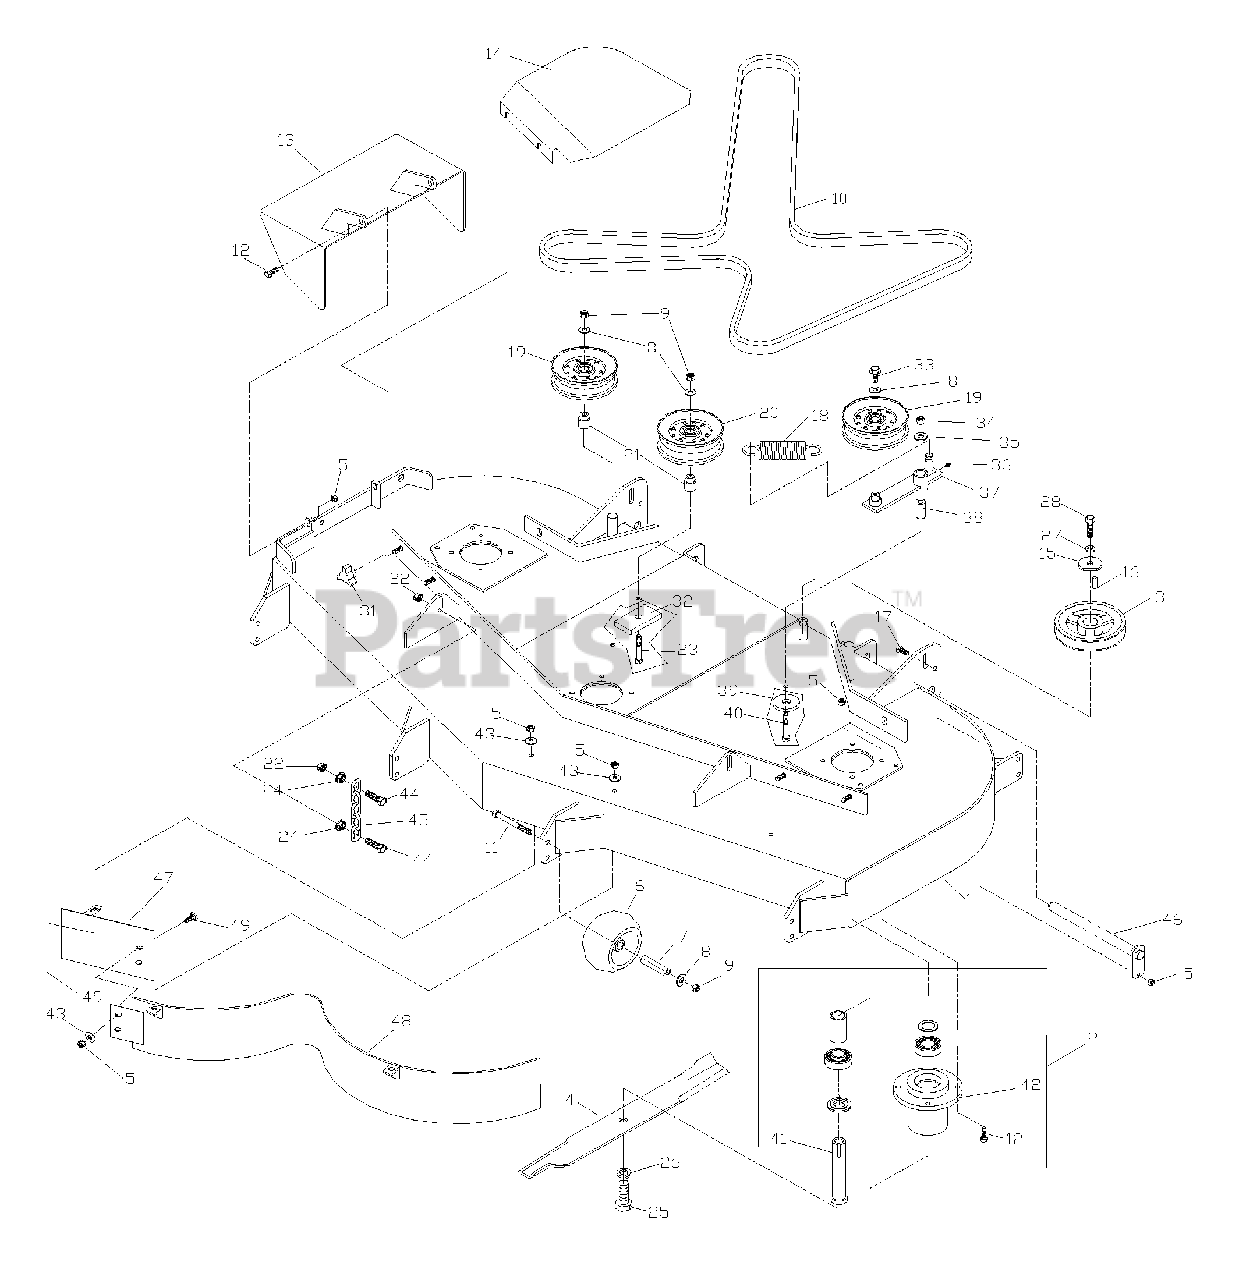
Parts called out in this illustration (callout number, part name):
1	DECK W/DECALS
2	CUTTER HOUSING ASM
2	BEARING KIT, CUTTER HOUSING
4	BLADE, 21"
5	NUT 5/16 LOCK
8	3/8 FLAT WASHER
9	NUT 3/8 LOCK
10	BELT
11	HCS 3/8 X 3.5
12	HCS 5/16 X 1.00
13	DISCHARGE CHUTE
14	BELT SHIELD RT
14	BELT SHIELD LT
16	KEY 1/4 SQ
17	HCS 5/16 X 750
19	PULLEY 1.31
20	PULLEY 1.62
21	IDLER BUSHING
22	NUT 7/16 LOCK
23	HCS 3/8 X 2.5
24	NUT 7/16 WHIZ
25	HCS 5/8F X 1.25
26	WASHER 5/8 LOCK
27	7/16 LOCK WASHER
28	HCS 7/16F X 1.5
32	PAD
33	HCS 3/8 X 1.0 SERR
34	NUT 1/2 NYLOC
35	WASHER 1/2 FLAT
36	ZERK
38	PIVOT BUSHING
39	SUPPORT WASHER
40	HCS 1/2 X 3.25
43	5/16 FLAT WASHER
44	HCS 7/16 X 1.5
45	LIFT CHAIN
47	BAFFLE , CENTER
48	BAFFLE, MAIN
49	RHSNB 5/16 X 5/8
